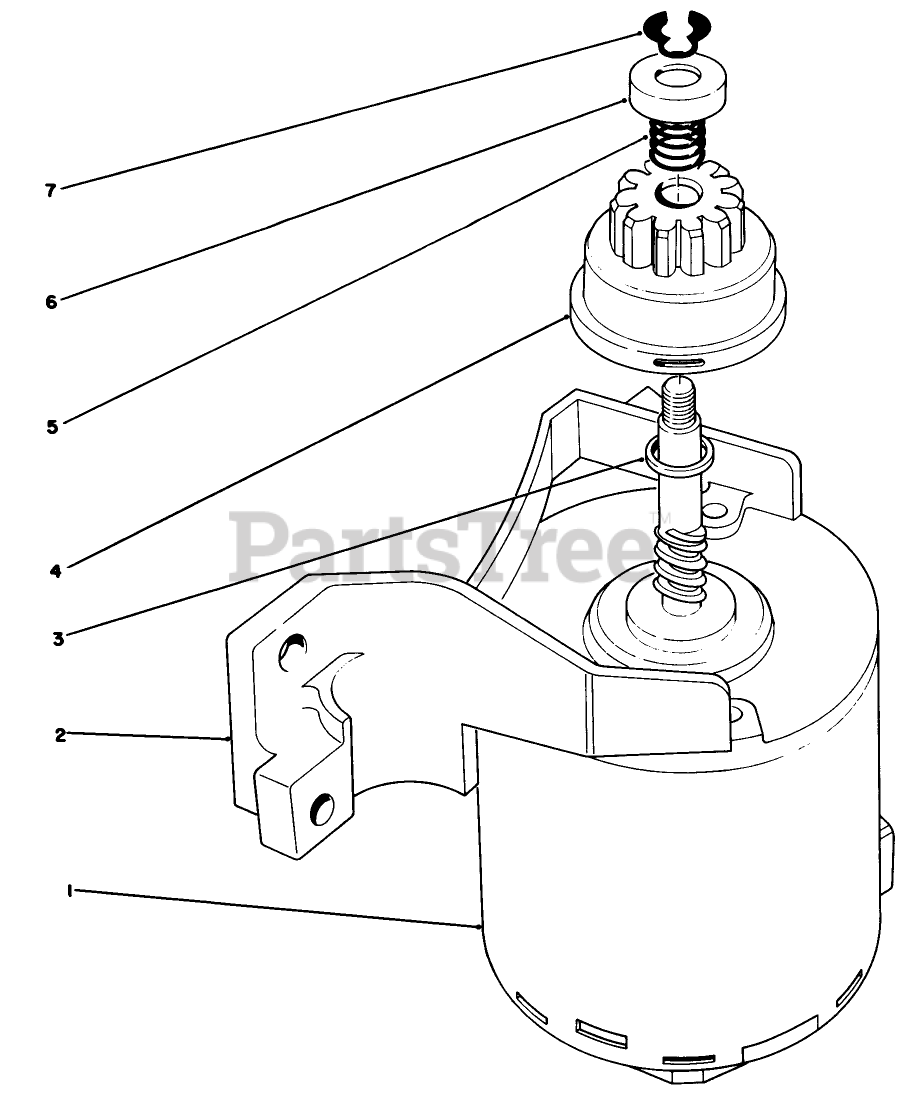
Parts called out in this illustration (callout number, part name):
1	END FRAME W/BRUSH
2	BRKT END FRAME
3	SPACER
4	PINION ASM
5	COMPRESSION SPRING
6	PINION STOP
7	RING-RETAINING
